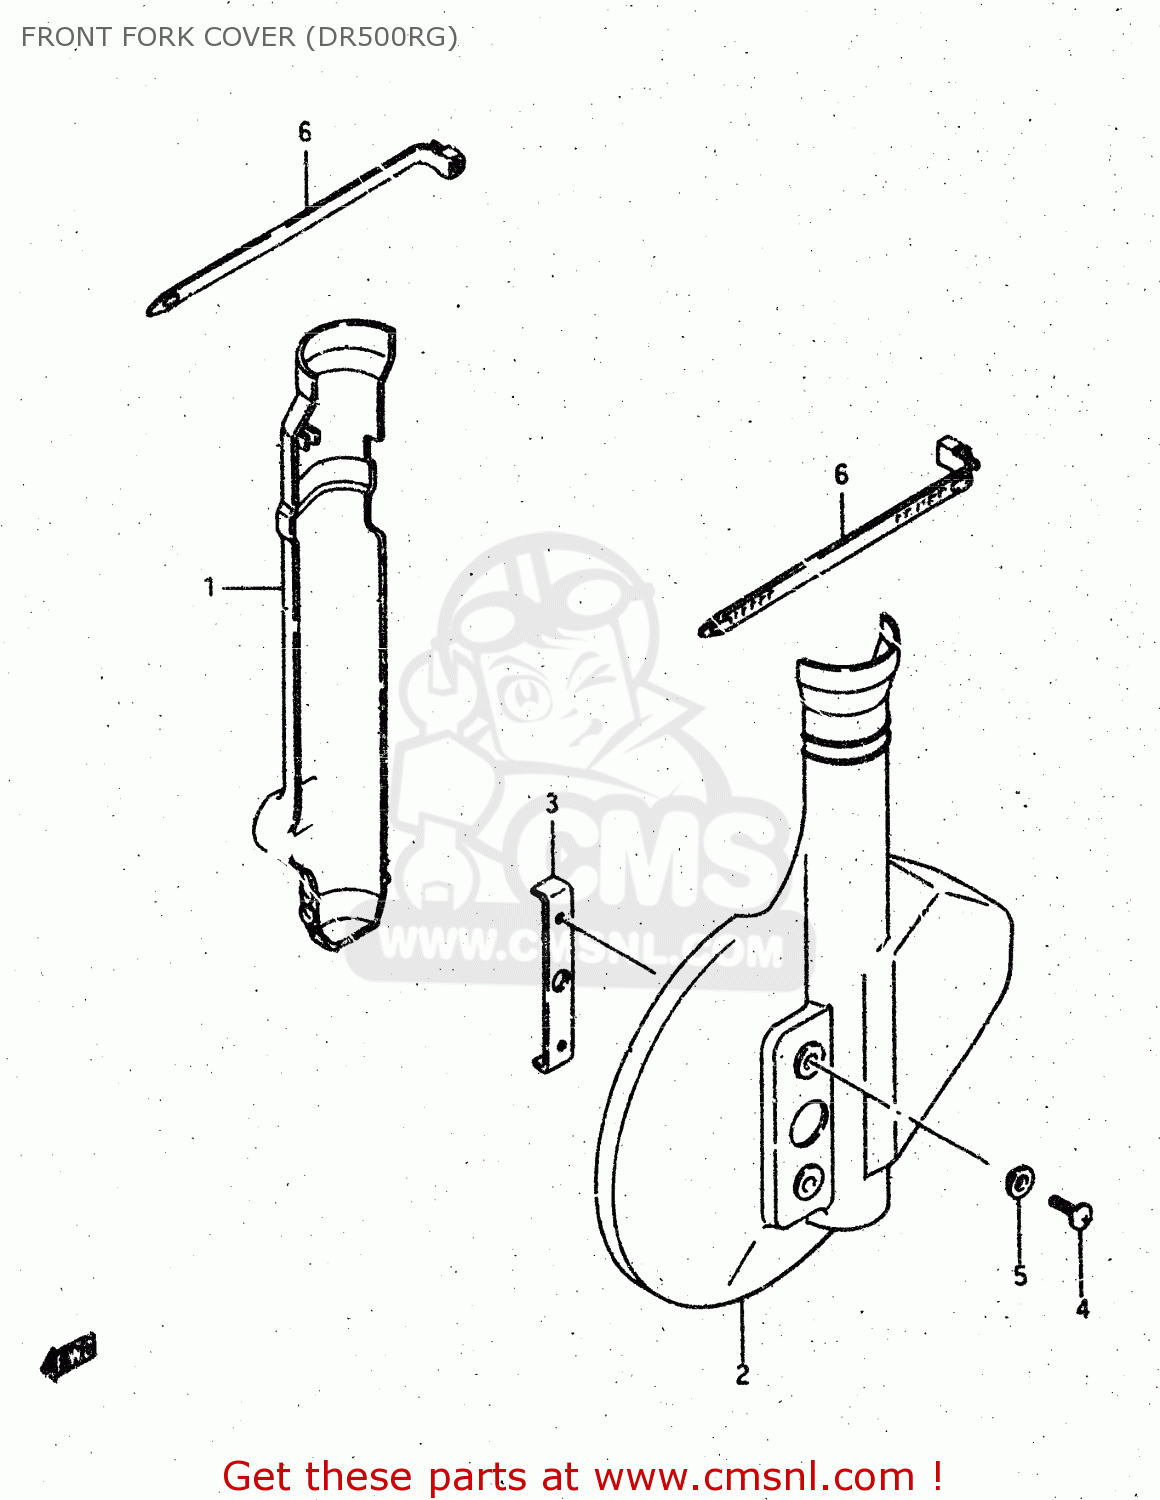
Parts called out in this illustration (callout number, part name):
1	PROTECTOR, FRONT FORK RH
2	PROTECTOR, FRONT FORK LH
3	PLATE, PROTECTOR
4	SCREW 6X12
5	WASHER
6	CLAMP
